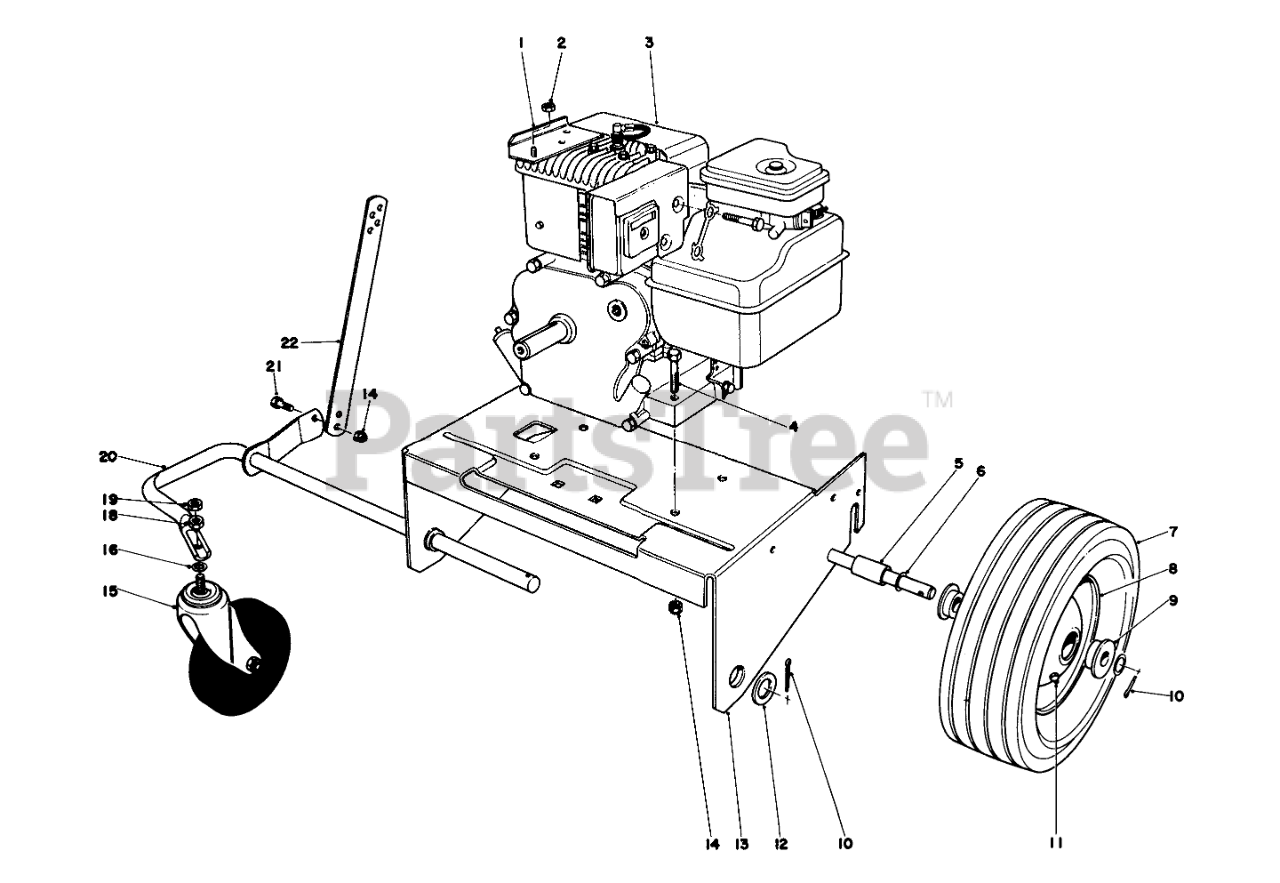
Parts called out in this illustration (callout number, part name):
1	MOUNTING BRKT WA
2	NUT-LOCK, NI
3	Engine
4	SCREW-HH
5	SPACER-AXLE
6	WASHER
7	3.50X10 SEMIPNEU TIRE
8	Rim
9	BUSHING
10	PIN-COTTER
11	FITTING-GREASE
12	WASHER-FLAT
13	BLWR ENG MTG PLT WA
14	NUT-LOCK, CONE
15	CASTER
16	WASHER-LOCK/INT
18	NUT-HH
19	1/2-13 CONELOCK NUT
20	FRT WHL SUPPORT WA
21	SCREW-HH
22	HT ADJ BAR
